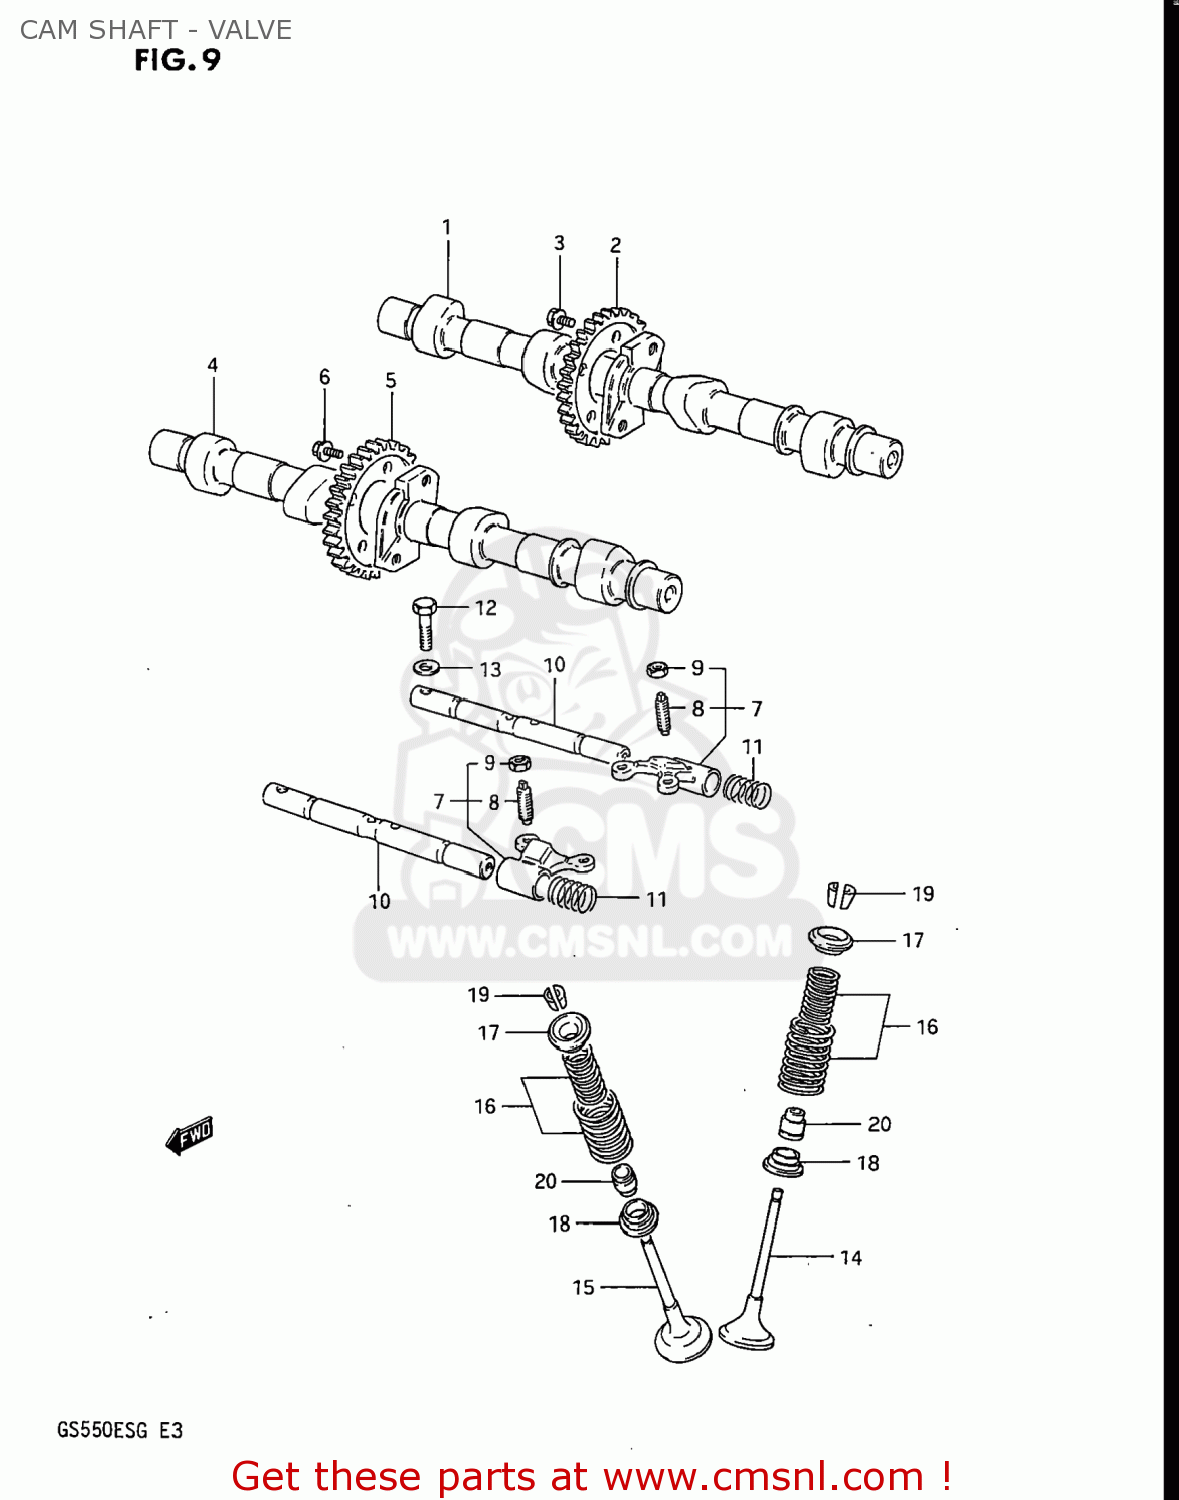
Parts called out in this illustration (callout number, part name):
1	CAMSHAFT,INTAKE
2	SPROCKET,INTAKE CAMSHAFT
3	BOLT(7X11)
4	CAMSHAFT,EXHAUST
5	SPROCKET,INTAKE CAMSHAFT
6	BOLT(7X11)
7	ARM,VALVE ROCKER
8	SCREW,TAPPET ADJUSTING
9	NUT,ADJUSTING
10	SHAFT,VALVE ROCKER
11	SPRING
12	BOLT
13	WASHER, LOWER
14	VALVE,INTAKE
15	VALVE,EXHAUST
16	SPRING SET,VALVE
17	RETAINER,VALVE SPRING
18	SEAT,VALVE SPRING
19	COTTER VALVE
20	SEAL,OIL(5X10.5X8.4)
